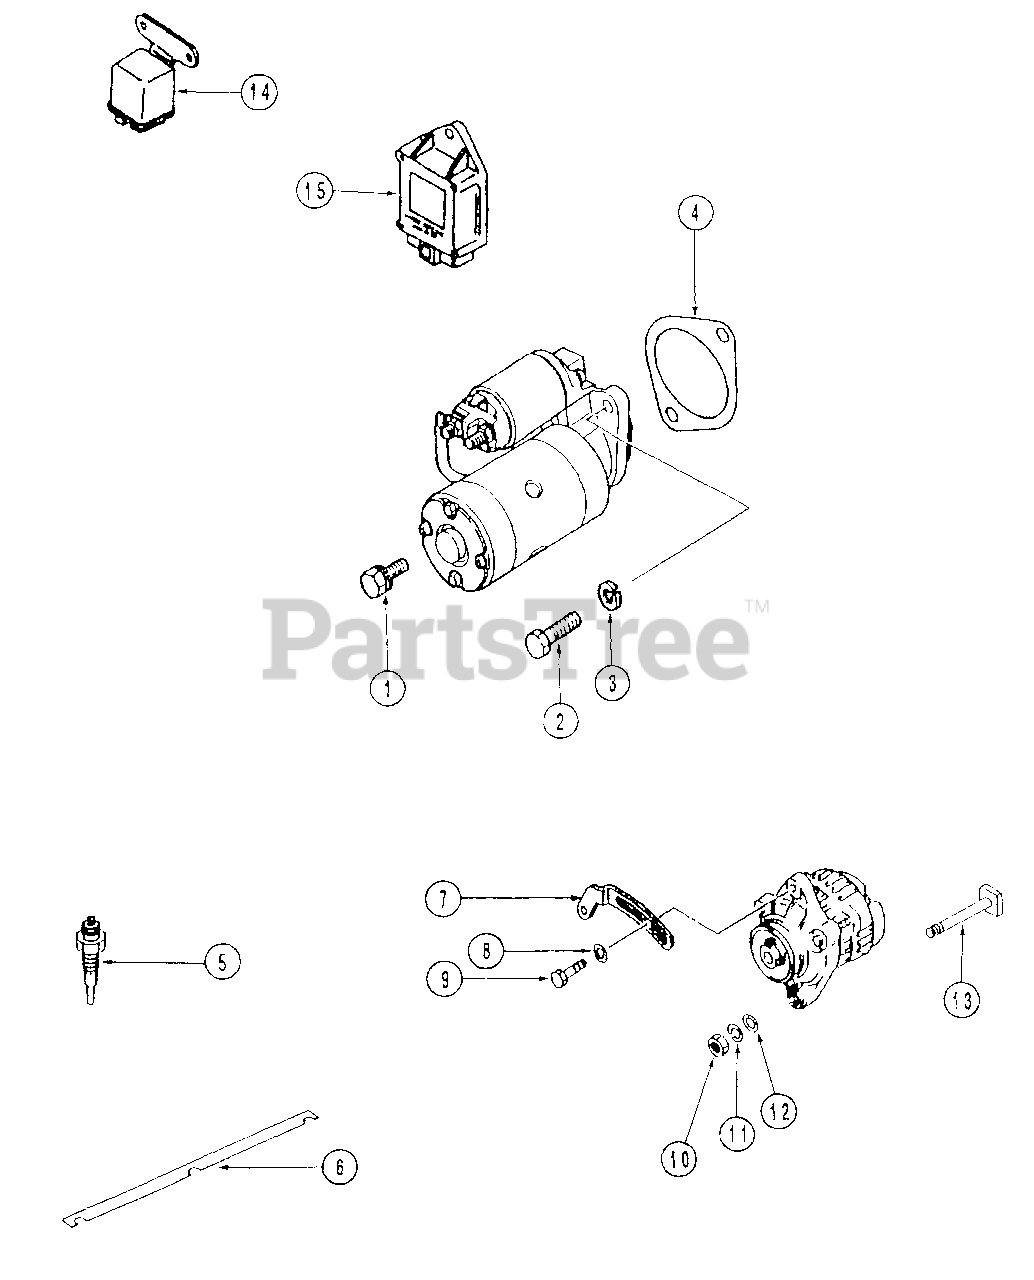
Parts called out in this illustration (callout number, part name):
1	Bolt, W/Washer
2	Bolt, Starter
3	Spring, Washer
4	Gasket, Starter
5	Plug, Glow
6	Plate, Connection
7	Plate, Adjusting
9	Bolt, Flange
11	Spring, Washer
12	Washer, Plain
13	Bolt, Alternator
14	Relay, Glow
15	Controller, Glow
